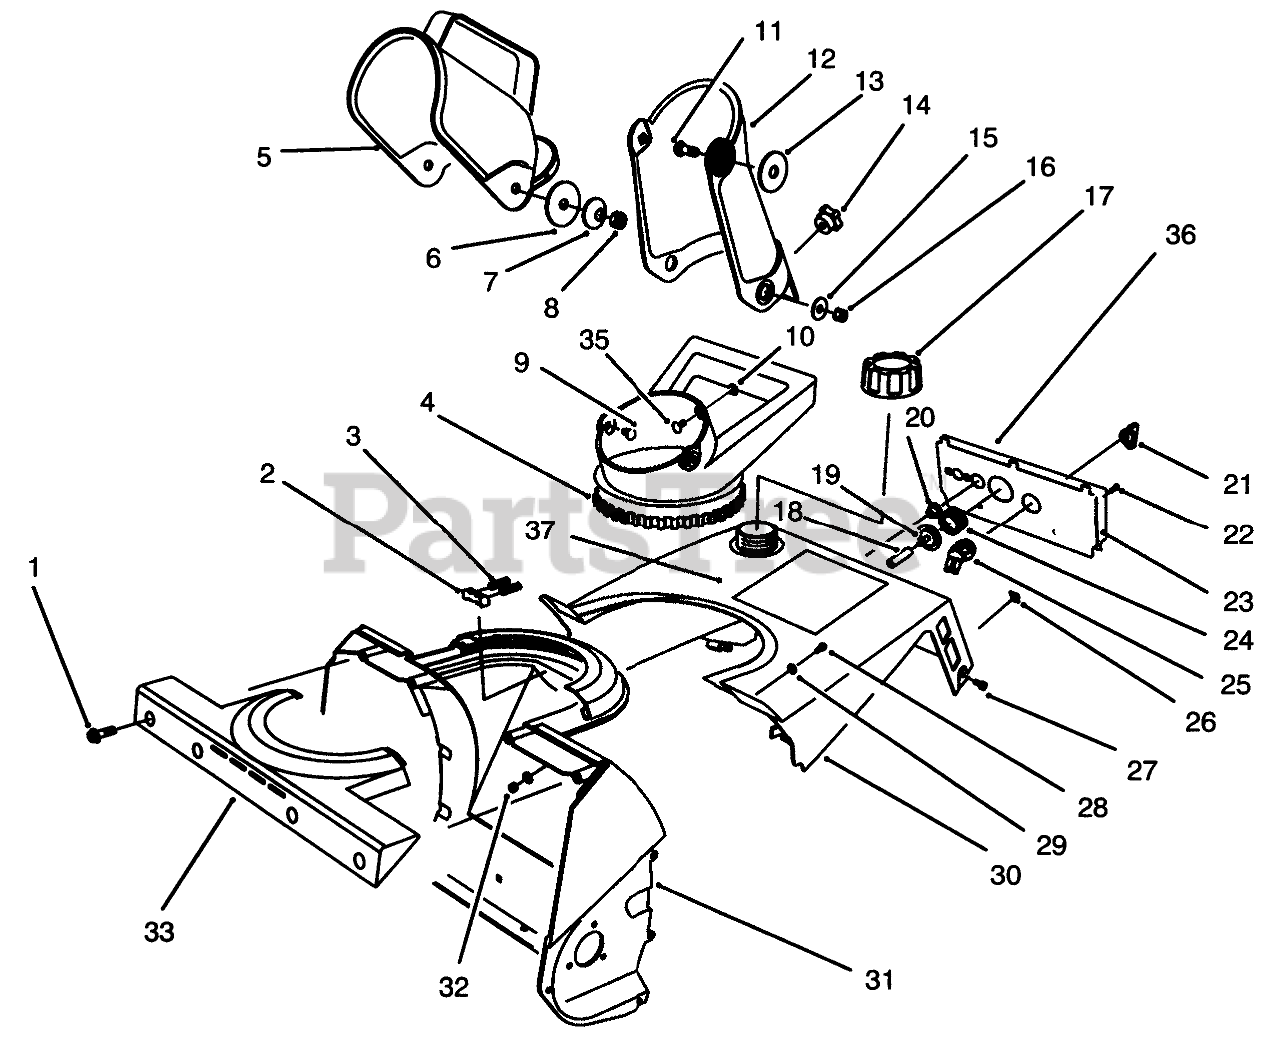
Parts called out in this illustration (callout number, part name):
1	SCREW-PLASTIC
2	DETENT-CHUTE
3	SPRING-COMPRESSION
4	HANDLE-CHUTE
5	DEFLECTOR-CHUTE
6	WASHER-FLAT
7	WASHER-BELLEVILLE
8	NUT-LOCK, NI
9	SCREW-HH
10	PUSHNUT-RETAINER, BOLT
11	BOLT-CARR
12	CHUTE
13	Washer-Rubber
14	KNOB-CHUTE
15	WASHER-FLAT
16	NUT-LOCK, NI
17	CAP-FUEL ASM
18	HOSE-PRIMER
19	BODY-PRIMER
20	GUIDE-ROPE, STARTER
21	KEY-IGNITION
22	SCREW-SHWH, THREAD FORMING
23	Panel-Control
24	BULB-PRIMER
25	SWITCH
27	SCREW-THREAD FORMING
28	SCREW-PPH
29	WASHER-FLAT
30	Shroud-Upper
31	HOUSING
32	NUT-LOCK, NI
33	RETAINER-CHUTE
35	SCREW-CARR
36	DECAL - CONTROL PANEL
37	DECAL - POWERLITE REC.
